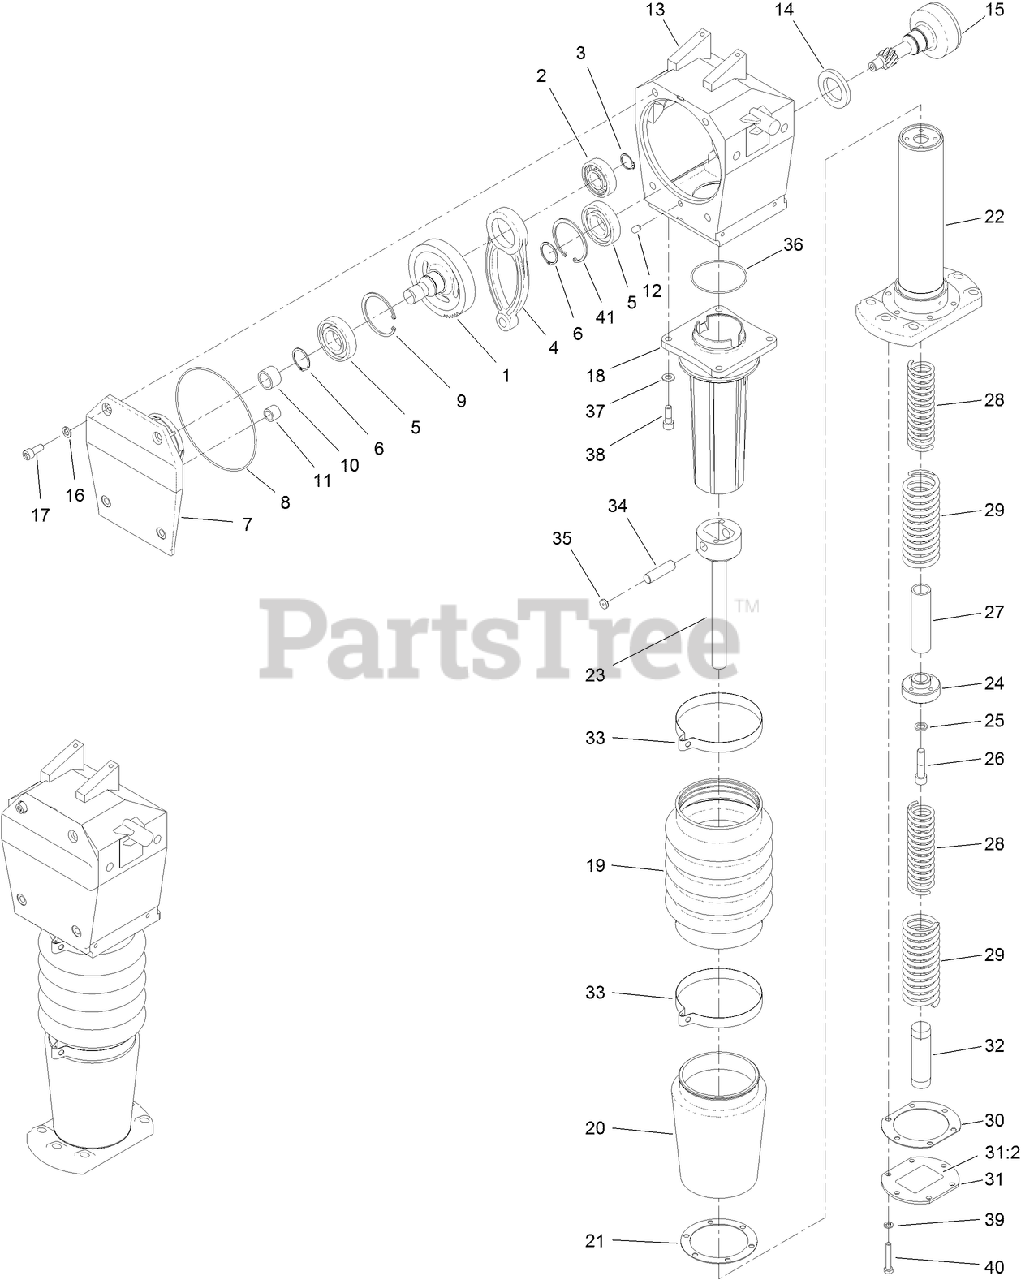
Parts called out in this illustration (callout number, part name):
1	GEAR-HELICAL
2	BEARING-BALL
3	RING-EXTERNAL
4	ROD-CONNECTING
5	BEARING-BALL
6	RING-SNAP, EXTERNAL
7	COVER-FRONT
8	O-RING
9	RING-INTERNAL
10	BEARING-NEEDLE
11	BEARING-NEEDLE
13	GEARCASE
14	SEAL-SHAFT
15	PINION
17	SCREW-HSH
18	GUIDE-TUBE
19	BOOT-STOMPER
20	COVER-HOUSING, SPRING
21	GASKET-HOUSING, SPRING COVER
22	HOUSING-SPRING
23	ROD-PISTON
24	PUCK-PISTON
25	WASHER-LOCK
26	SCREW-HSH
27	SNUBBER-SPRING, UPPER
28	SPRING-COMPRESSION, INNER
29	SPRING-COMPRESSION, OUTER
30	GASKET-COVER, SPRING
31	BOTTOM SPRING COVER ASM
31:2	DECAL-WARNING, SPRING
32	SNUBBER-SPRING, LOWER
33	CLAMP-BOOT, STOMPER
35	BUTTON-PIN, CAPTIVATOR
36	O-RING
37	WASHER-FLAT
38	SCREW-HSH
39	WASHER-LOCK
40	SCREW-HH
41	RING-INTERNAL
